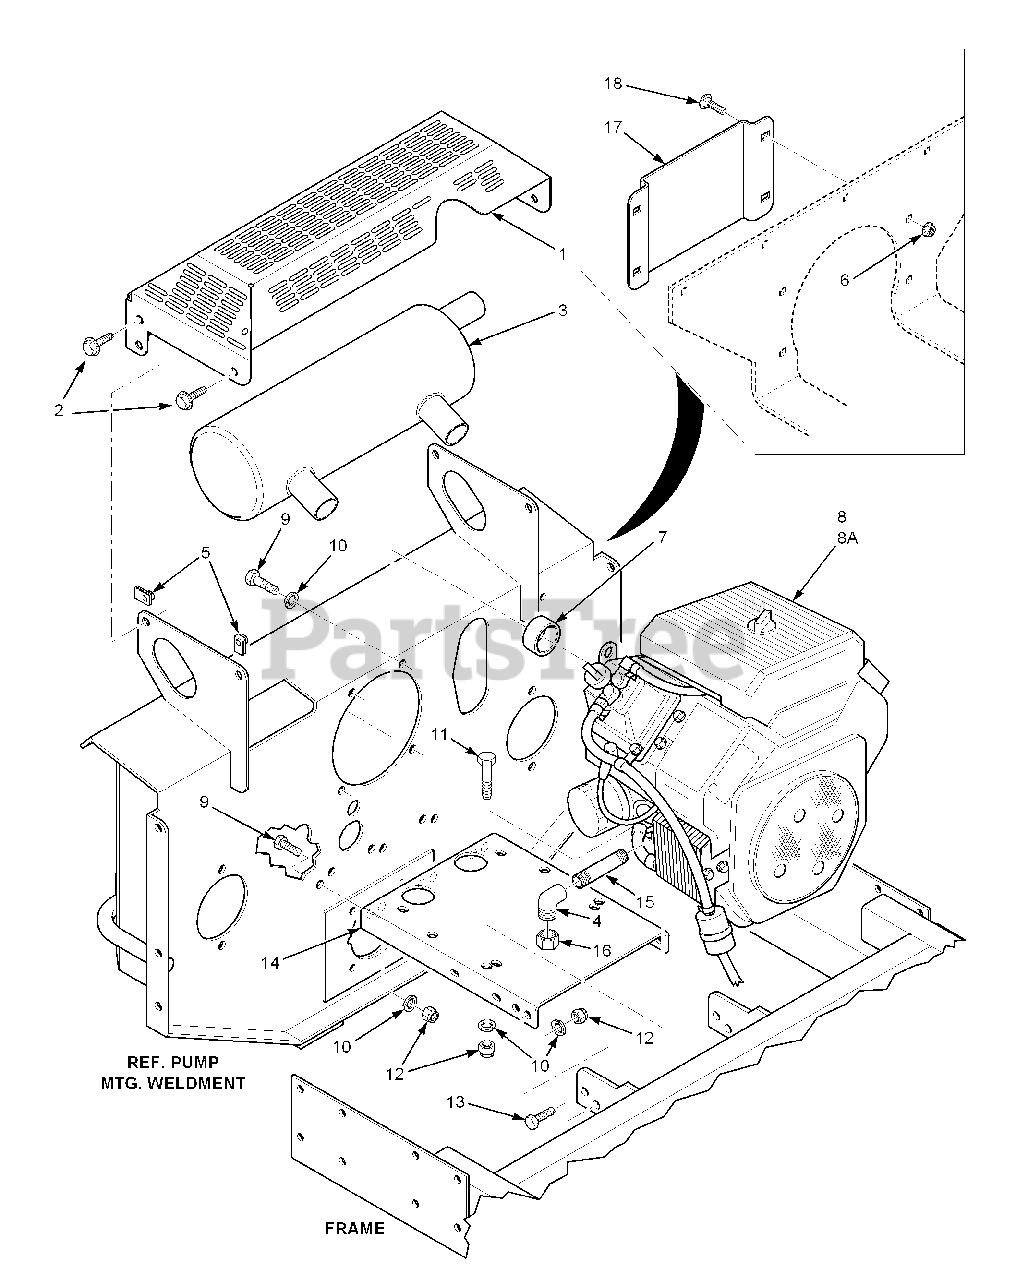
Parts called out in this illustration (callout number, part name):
1	Muffler Guard
2	Screw, Hex Serrated Flange 1/4-20 x 3/4"
3	Muffler, Part Of Engine
4	Screw, #10-16 x 1/2"
5	U-Nut, 1/4-20
6	Exhaust Elbow
7	Spacer, Engine
8	Engine, Kohler 22CH
8	Engine, Kohler 25CH
9	Bolt, Hex Head 3/8-16 x 1"
10	Lockwasher, 3/8" Spring
11	Bolt, Hex Head 3/8-16 x 1-3/4"
12	Nut, Hex Elastic Stop 3/8-16
13	Bolt, Hex Head 3/8-16 x 1-1/4"
14	Plate, Engine Mounting
15	Extension, Oil Drain 2"
16	Pipe Cap, Hex 3/8"
17	Rear Cover
18	Bolt, Carriage 5/16-18 x 3/4"
19	Nut, Hex Serrated Flange 5/16-18
20	Street Elbow, 3/8" NPT
